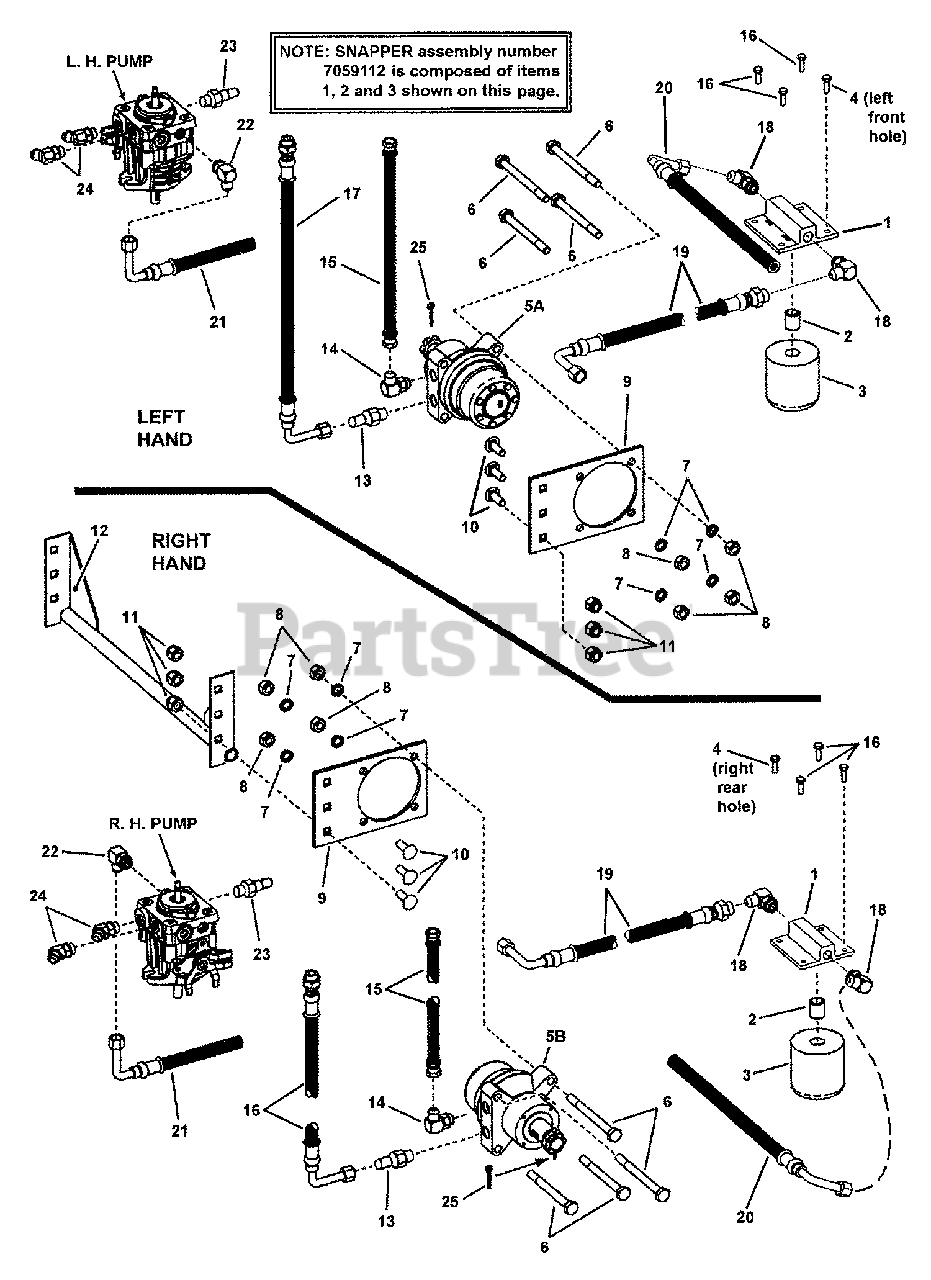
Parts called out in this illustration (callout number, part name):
1	MOUNT, Oil Filter
2	FITTING, Straight 1-12 UNF Thread
3	FILTER, Oil
4	SCREW, 3/8-16 x 3/4" Hex Washer Self-Tap
5A	MOTOR, Hydraulic, Left Hand
5B	MOTOR, Hydraulic, Right Hand
6	BOLT, 1/2-13 x 6" Hex Head Cap GR 5
7	WASHER, 1/2" Split Lock
8	NUT, 1/2-13 HEX
9	PLATE, Mounting
10	BOLT, 1/2-13 x 1-1/2" Square Neck Carriage, GR 5
11	NUT, 1/2-13 Hex Nyloc
12	WELDMENT, Rear Crossbrace
13	CONNECTOR, Straight Hydraulic (Parker # 8-10 F5OLO-S)
14	CONNECTOR, 90-Degree Hydraulic (Parker # 8-10 C5OLO-S)
15	HOSE, 13-3/4" Hydraulic (Parker # F436BKJCJC080808-13-75)
16	SCREW, 5/16-18 x 3/4" Hex Washer Self-Tap
17	HOSE, 17-1/2" Hydraulic (Parker # F436BKJCJ5080808-17.5)
18	CONNECTOR, 90-Degree Hydraulic (Parker # 8 C5OLO-S)
19	HOSE, 18-1/2" (Parker R836BKJCJ9090808-18.5)
20	HOSE, 12-1/4" (Parker # R836BKJ9NR080008-12.5)
21	HOSE, 6-1/2" (Parker # R836BKJ9NR080008-6.5
22	CONNECTOR, 90-Degree Hydraulic (Parker # 8-6 C5OLO-S
23	CONNECTOR, Straight Hydraulic (Parker # 8-6 F5OLO-S)
24	CONNECTOR, 45-Degree Hydraulic (Parker # V5OLO-S)
25	PIN, 9/64 x 1-1/2" Cotter
